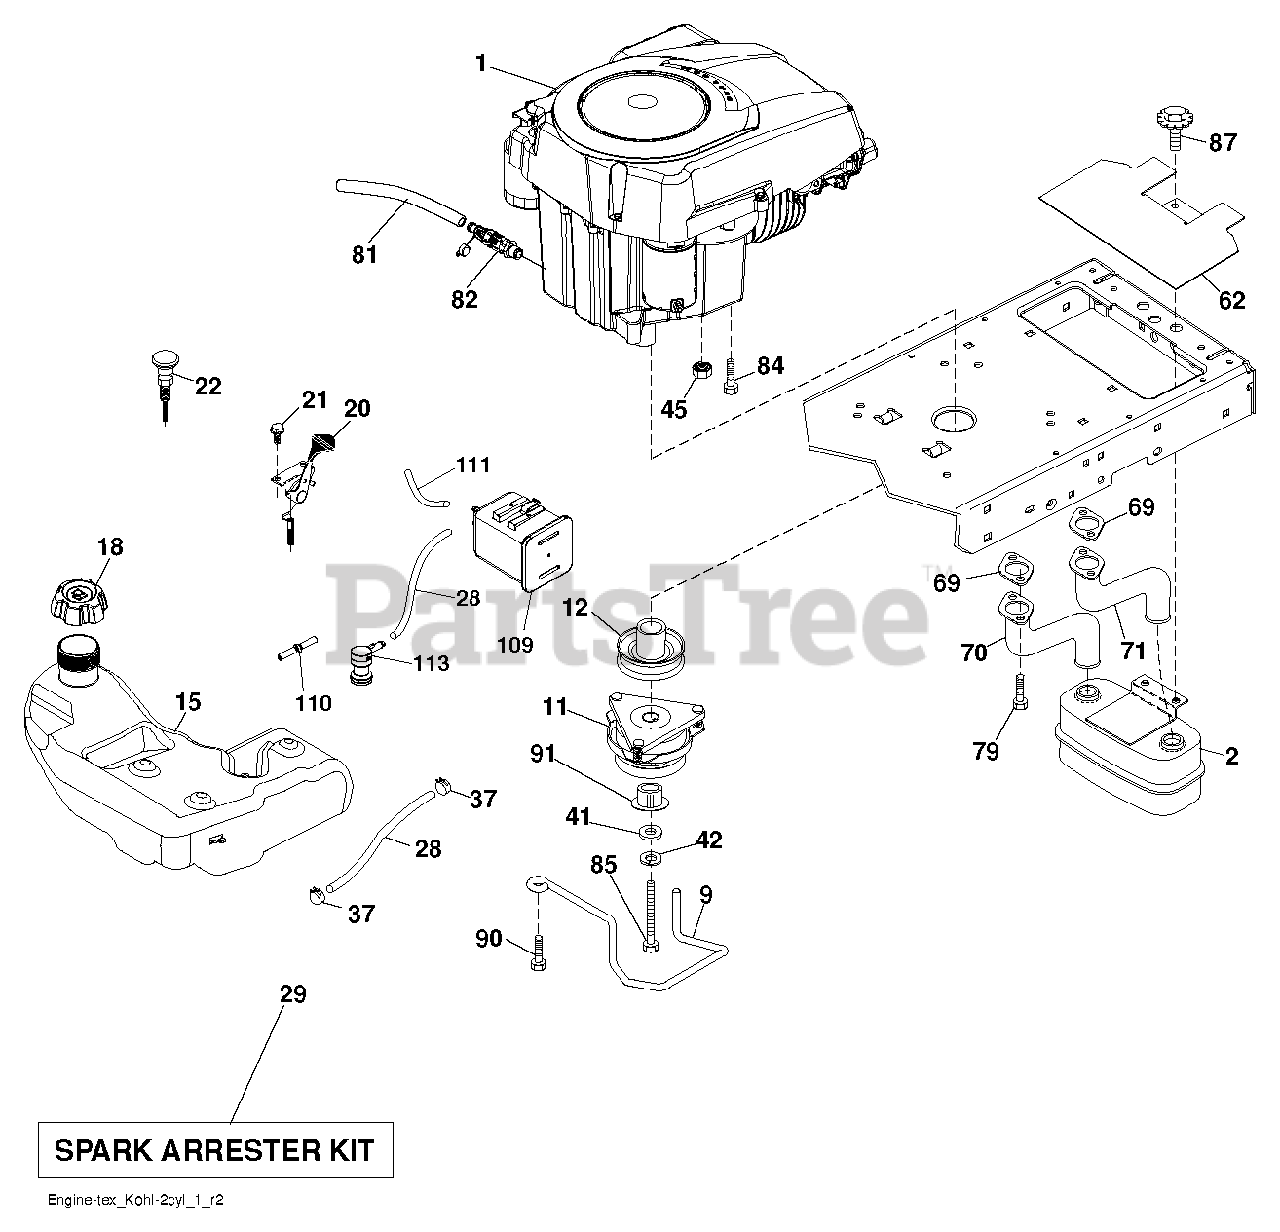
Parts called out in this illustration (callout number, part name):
2	MUFFLER.TWIN.CYL.LOW.TONE
9	KEEPER.BELT.ENGINE.4.2
11	CLUTCH MZ ZTR GT.48/54"1.125"
12	PULLEY ENGINE
15	RP TANK.ASM.FUEL.4GA.CARB
18	RP CAP ASM
20	THROTTLE CONTROL
21	SCREW.#10 X 0.750.BOS
22	CONTROL.CHOKE.ERGO.PUSH-IN.BLA
28	LINE.FUEL.64"REAR.EMIS
29	KIT.SPARK ARRESTOR 794945 B&S
37	HOSE CLAMP
42	LOCKWASHER
45	NUT
62	RP SHIELD HEAT MUFFLER
69	GASKET.EXHAUST.KOHL.CV18-CV26
70	RP.PIPE-EXHAUST LH
71	Tube Exhaust RH
79	SCREW.SOCKET HD.5/16-1
81	TUBE, DRAIN OIL ASM.
82	VALUE.OIL.DRAIN
84	SCREW 3/8-16X1
85	BOLT HEX 7/16-20 X 3.75 GR. 5
87	BOLT.5/16-18UNCX1.W/SEMS.BLK
90	SCREW 3/8-16X1
91	BUSHING.1.375OD
109	CANNISTER, CARBON
110	VALVE.ASM.ANTI-SLOSH
111	RP PURGE LINE
113	VALVE.SLANT.CARTRDG.90 DEG.TEX
